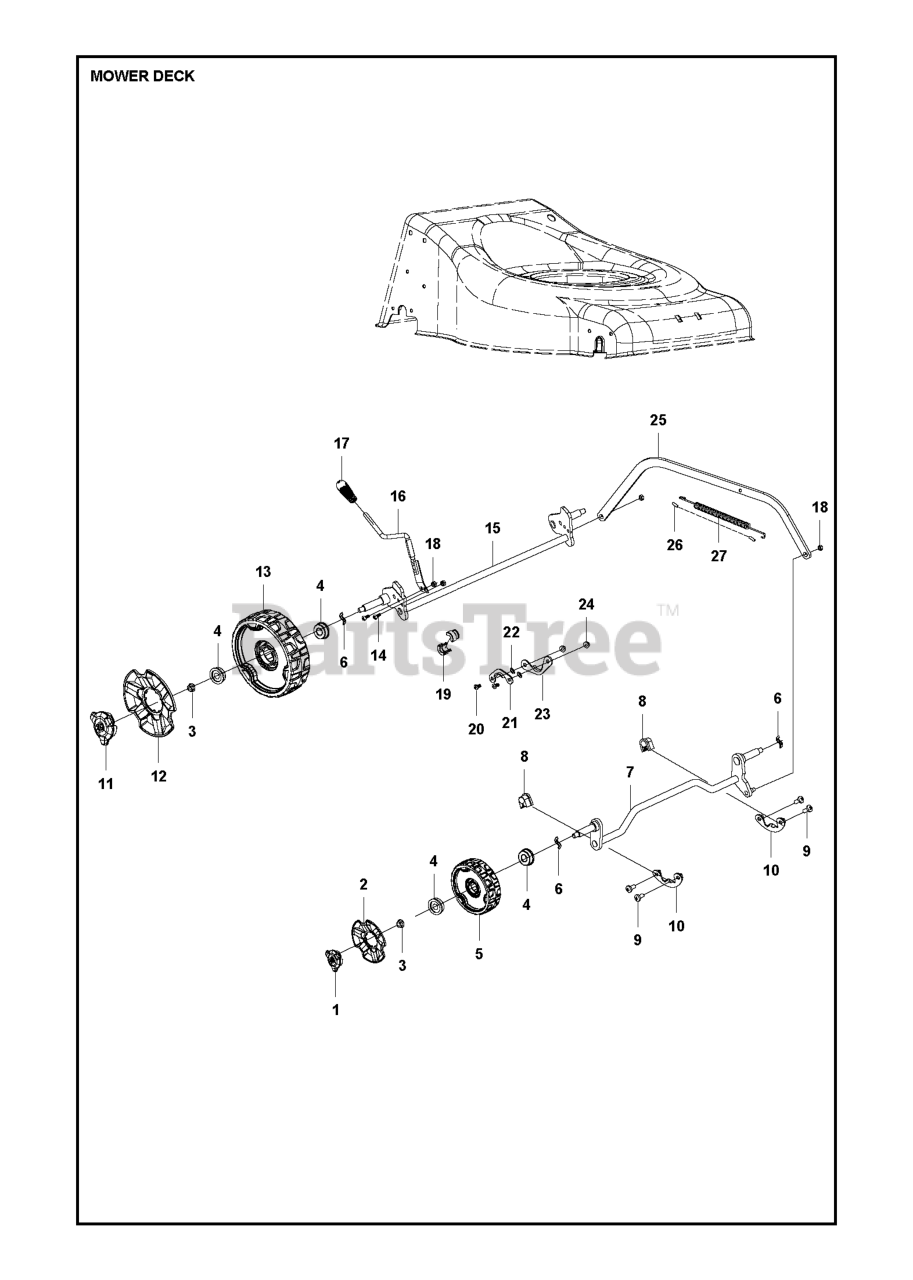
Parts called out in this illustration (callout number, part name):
1	WHEEL COVER 6" #25340700101
3	LOCKING BOLT M8,GB6187.1 #2680
6	WASHER Ï?12 #26800706202
11	WHEEL COVER 8" #25341000101
12	WHEEL COVER 8" #25341100101
13	WHEEL #25341300101
14	WASHER M6*14 #26800203001
16	HANDLE ASSY
17	KNOB HEIGHT ADJUSTMENT #25341
18	LOCKING BOLT M6,GB889.1 #26800
19	COVER AXLE #25235300101
20	SCREW M6*16 #26800204601
21	FIXING PLATE #26300314601
22	O-RING #25100175201
23	FIXING PLATE #26300124401
24	LOCK NUT M6,GB/T6187.1-2000 #2
26	TUBING #29000300101
27	SPRING #26801103903
